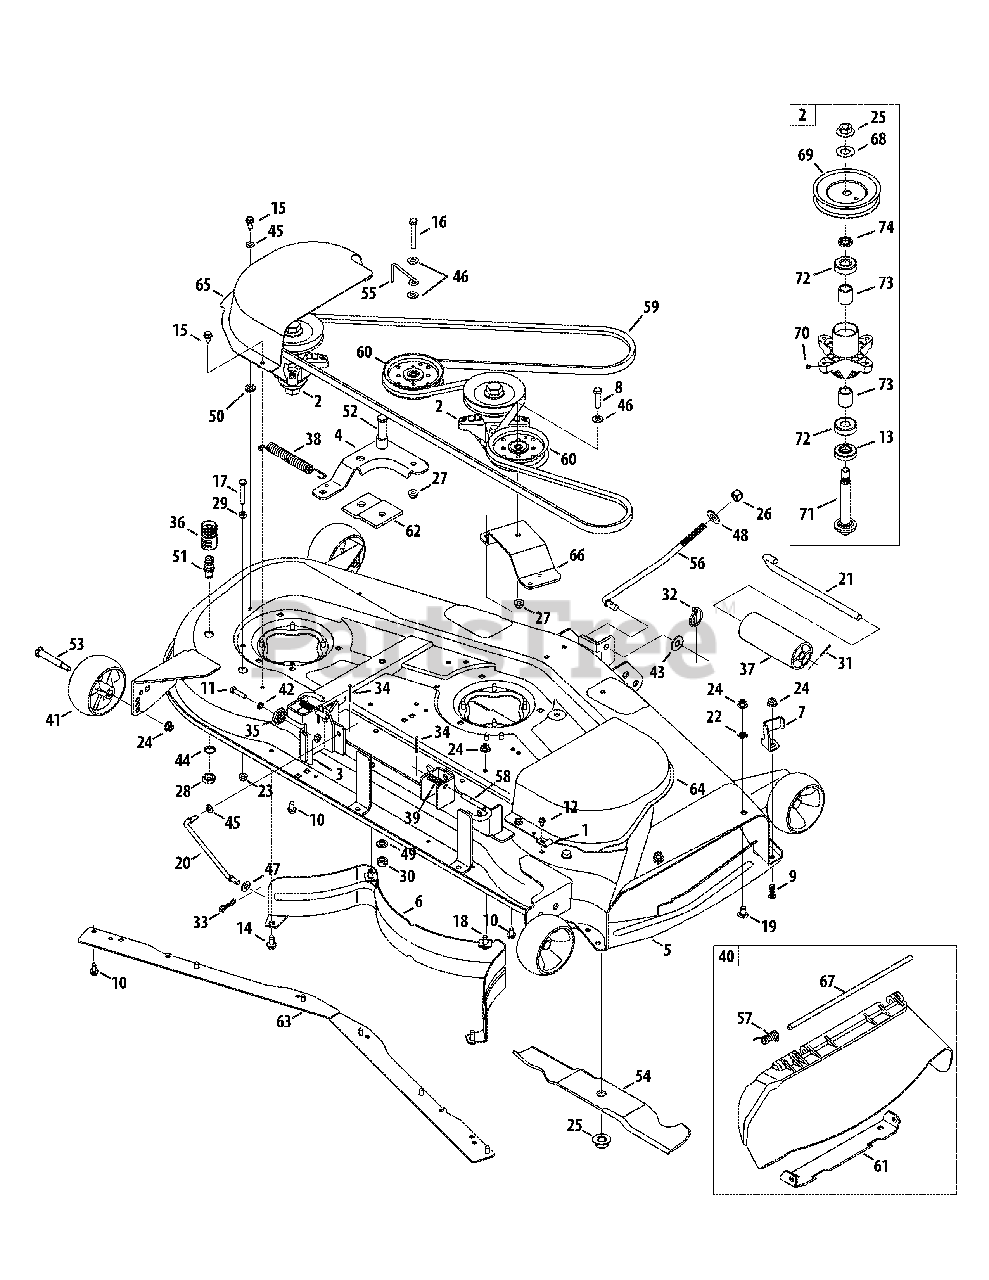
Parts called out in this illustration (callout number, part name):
1	Bracket, Hook, Retainer
2	Spindle Assembly, Pulley, 5.39 Dia.
3	Bracket Assembly, Deck, Hanger LH
4	Idler Assembly, Arm, 54"
5	Deck Assembly, 54"
6	Baffle, Rear
7	Stop, Chute, Deflector
8	Hex Screw, 3/8-16, 1.75, Gr5
9	Hex Screw, 3/8-16, 1.00, Gr5, Spec
10	Screw, Self-tapping, 5/16-18, .750,
11	Hex Screw, 5/16-18, 1.25, Gr5, Std
12	Screw, Self-tapping, 1/4-20, 0.500
13	Spacer, .79 x 1.82 x .55lg.
14	Screw, Self-tapping, 3/8-16, 0.750
15	Screw, Self-tapping, 5/16-18, 0.875
16	Hex Screw, 3/8-16, 2.50, Gr5, Std
17	Hex Screw, 5/16-18, 2.00, Gr5, Std
18	Bolt, Carriage, 3/8-16, 1.00, Gr5
19	Bolt, Carriage, 3/8-16, 0.75, Gr1
20	Rod, Support, Deck
21	Roller Pin-1/2 Dia. x 7.31
22	Nut, Push, 3/8
23	Nut, Flange Lock, 5/16-18, Nylon
24	Nut, Flange Lock, 3/8-16, Nylon
25	Nut, Flange, 5/8-18
26	Nut, 1/2-13
27	Nut, Flange Lock, 3/8-16, GrF
28	Nut, Hex, M16-1.5
29	Nut, Hex, 5/16-18, Gr5
30	Nut, Hex Lock, 1/2-13, GrB
31	Pin, Cotter, 3/32, 1.0
32	Pin, Lynch, .1875
33	Pin, Cotter, Bow-Tie
34	Pin, Cotter, 1/8 x 1.25
35	Gear, Deck, Adjustment
36	Coupler, Water
37	Roller, Front
38	Spring, Extension, .85 OD x 6.415
39	Spring, Compr’, .53 OD x 1.75
40	Chute Assembly
41	Wheel, Deck, 5.0 Dia. Ball
42	Washer, Lock, 5/16, Regular Duty
43	Washer, Flat, .531 x 1.25 x .100
44	Washer, Lock, 5/8, Int Tooth
45	Washer, Flat, .344 X .688 X .065
46	Washer, Flat, .406 x .875 x .059
47	Wash, Thrust, .375x.70x.030
48	Washer, Bell, .63 x 1.25 x .18
49	Washer, Lock, 1/2 , Regular Duty
50	Washer, Flat, .407x.812x.135
51	Port, Water
52	Bolt, Shoulder, .625 x 2.50, 1/2-13
53	Bolt, Shoulder, .496 x 2.50, 3/8-16
54	Blade, 18.50 Star 2 In 1
55	Rod, Keeper
56	Deck Lift Rod, Front, 11.7
57	Spring, Torsion, .44 I.D. x 2.0,
58	Rod, Deck Release
59	Belt, V-Type
60	Pulley, Idler, 4.25"Dia.
61	Bracket, Chute 50/54"
62	Bracket, Stabilizer, Pulley
63	Skirt, Deck, 54"
64	Cover, Belt, RH 50"
65	Cover, Belt, LH 50"
66	Bracket, Idler, Stationary
67	Pin, Hinge, .3175 Dia. x 14.06 ,1
68	Washer, Flat, .760 X 1.50 X .120
69	Pulley, Deck, 5.39 Dia.
70	Lube Fitting, 3/16
71	Shaft, Spindle, 5.75 Lg.
72	Bearing, Ball, .787id x 1.85 Od x .551
73	Spacer, .80 x 1.10 x 1.322
74	Spacer, .790 x 1.25 x .175
